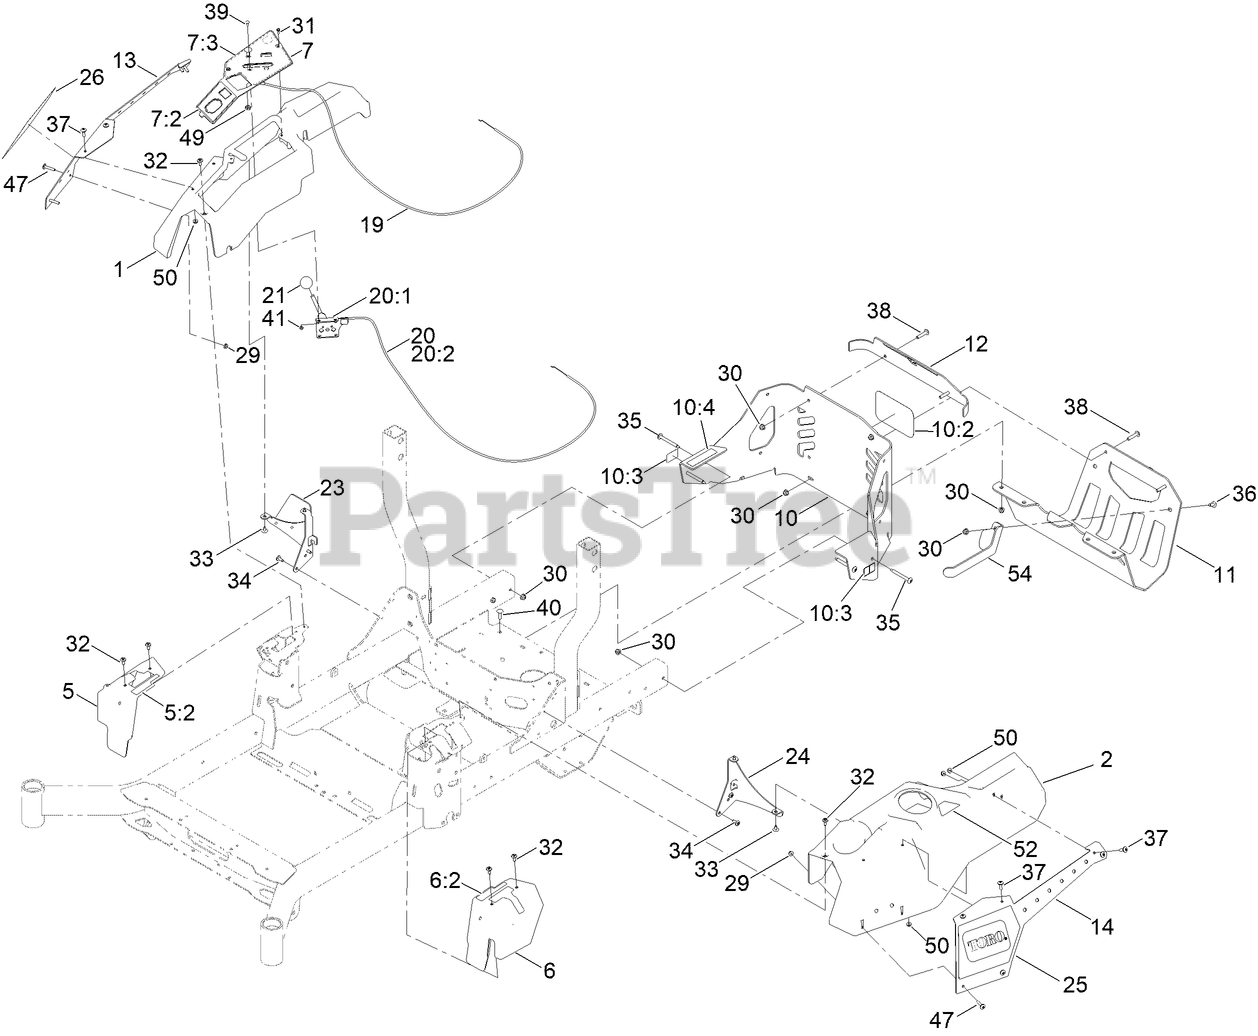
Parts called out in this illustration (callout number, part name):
1	CONSOLE-RH
2	CONSOLE-LH
5	COVER-CONTROL, MOTION (RH)
5:2	DECAL-CONTROL, MOTION (RH)
6	COVER-CONTROL, MOTION (LH)
6:2	DECAL-CONTROL, MOTION (LH)
7	CONTROL PANEL ASM
7:2	DECAL-PANEL, CONTROL
7:3	DECAL - PANEL CONTROL
10	REAR GUARD ASM
10:2	DECAL
10:3	DECAL-WARNING
10:4	DECAL-ARRESTOR, SPARK
11	GUARD-MUFFLER [BLACK]
12	TRIM-UPPER REAR
13	COVER, POD RH
14	COVER-LH
19	CABLE-CHOKE CONTROL
20	THROTTLE CONTROL ASM
20:1	LEVER-THROTTLE
21	KNOB-BALL
23	SUPPORT-CONSOLE, RH
24	BRACKET-CONSOLE, LH
25	DECAL-PLATE, LH
26	DECAL-PLATE, RH
29	NUT-HF
30	NUT-HF, NI
31	SCREW-HWH
32	SCREW-SHOULDER
33	SCREW-TORX
34	SCREW-TORX
35	SCREW-TORX
36	SCREW-TORX
37	SCREW-TRUSS
38	SCREW-TORX
39	BOLT-CARR
40	SCREW-CARR
41	NUT-LOCK, NI
47	SCREW-TRUSS
49	NUT-HJ
50	NUT-KEPS
52	DECAL-FILL, FUEL
54	BRACKET-GUARD, MUFFLER
